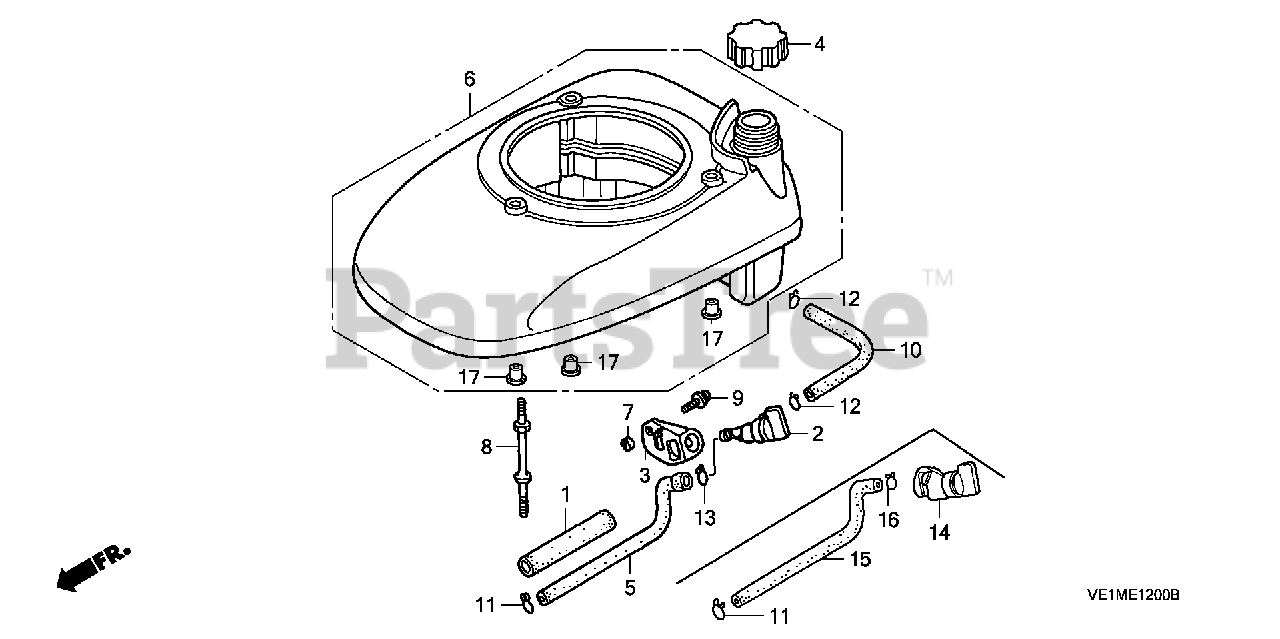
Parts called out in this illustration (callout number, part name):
1	RUBBER, SUPPORTER (107MM)
2	PETCOCK ASSY.
3	BRACKET, PETCOCK
4	CAP ASSY., FUEL TANK
5	TUBE, FUEL
6	COVER, FAN *R280* (POWER RED)
7	COLLAR, FR. TURN SIGNAL
8	BOLT, STUD (H=42.5MM)
9	SCREW-WASHER (5X10)
10	BULK HOSE, FUEL (5.5X3000) (5.3X150)
11	CLIP, TUBE (B8)
12	CLIP, TUBE (B10)
13	CLIP, TUBE (C9)
14	PETCOCK ASSY.
15	TUBE, FUEL
16	CLIP, TUBE (B8)
17	COLLAR, FAN COVER
